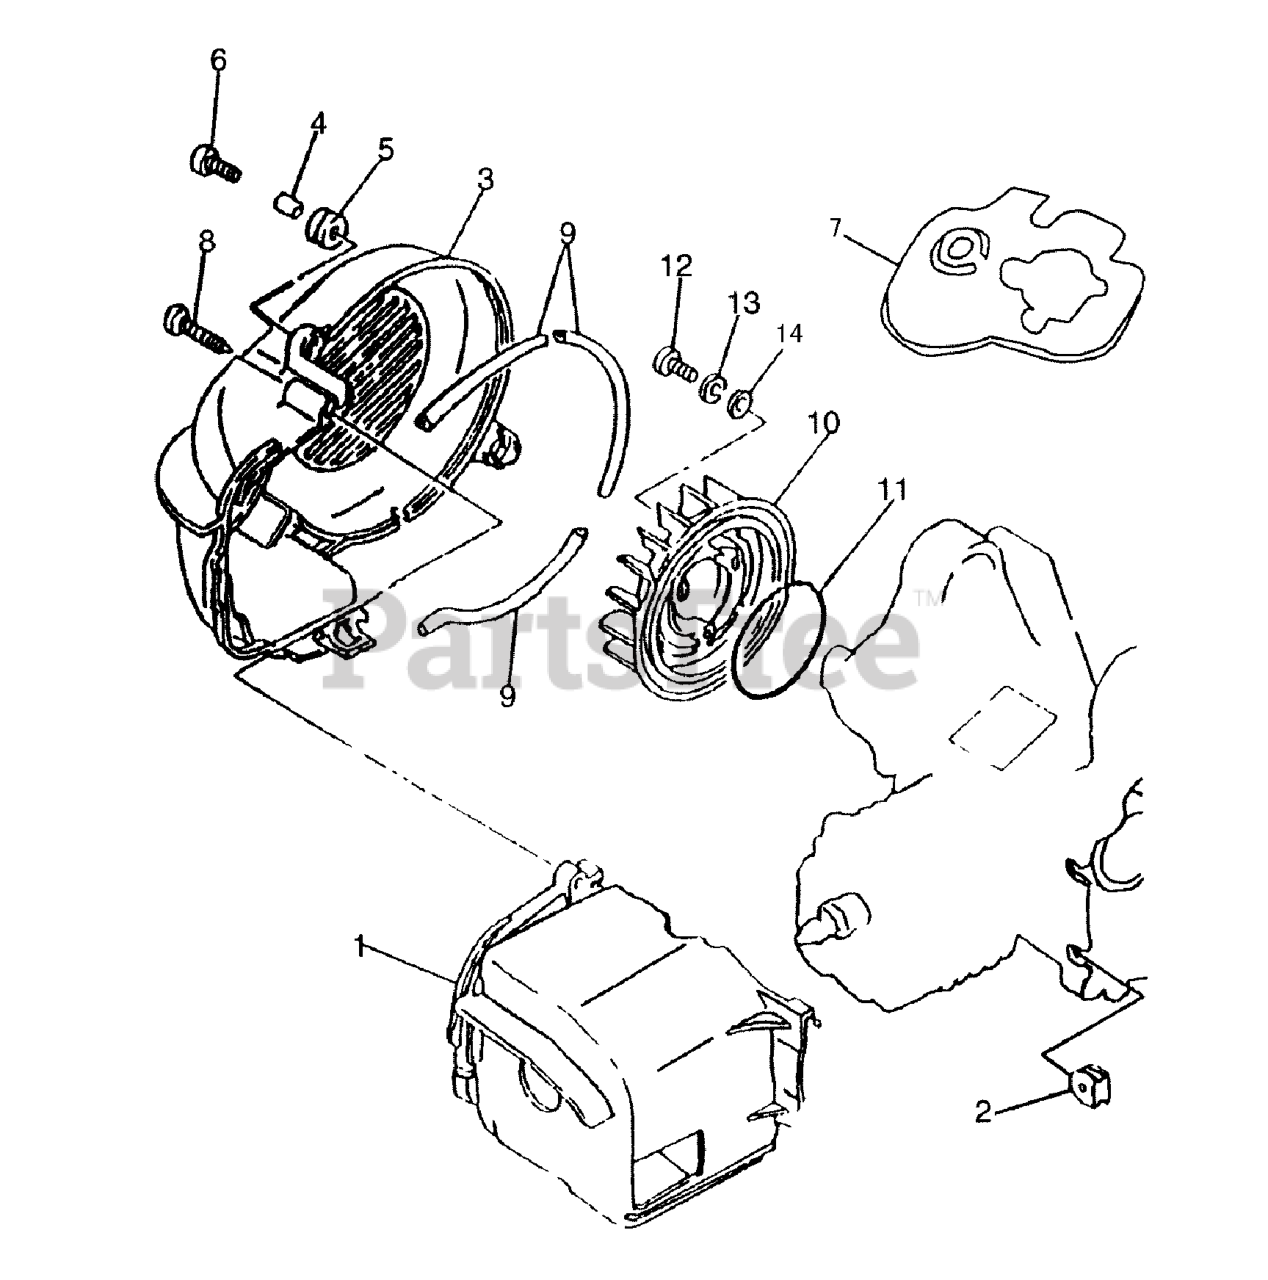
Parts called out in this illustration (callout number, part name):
1	COWLING, CYLINDER
2	GROMMET
3	COWLING, FAN
5	GROMMET
9	MOLD, COWLING
10	FAN ASSY
11	RUBBER RING
